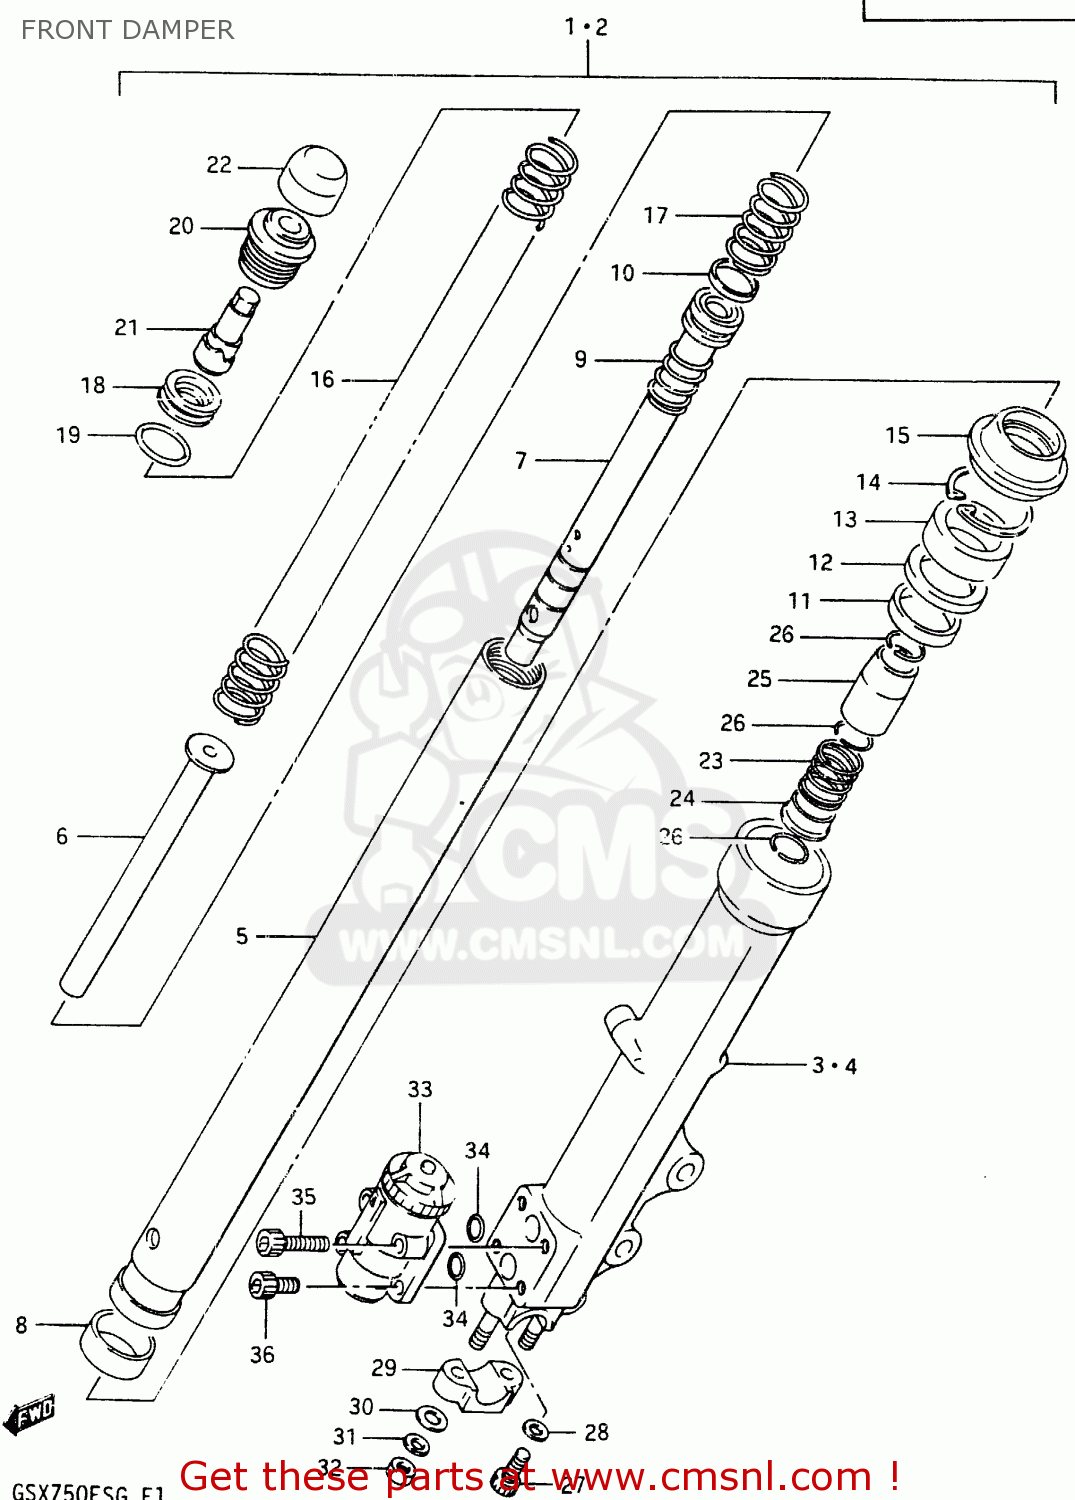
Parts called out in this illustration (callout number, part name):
1	DAMPER ASSY, RH
2	DAMPER ASSY, LH
3	TUBE, OUTER RH (BLACK)
4	TUBE, OUTER LH (BLACK)
5	TUBE, INNER
6	SEAT, INNER TUBE
7	CYLINDER
8	PISTON
9	SPRING REBOUND
10	RING,PISTON
11	BUSHING,GUIDE
12	SPACER,SEAL
13	OIL SEAL,FRONT FORK
14	CIRCLIP,INNTERNAL
15	SEAL,DUST
16	SPRING
17	SPRING, LOWER
18	SEAT,FRONT FORK SPRING
19	O RING
20	CAP,FORK INNER TUBE
21	ADJUSTER,SPRING
22	CAP
23	SPRING, VALVE
24	VALVE, OIL LOCK PIECE
25	PIECE, OIL LOCK
26	RING,STOPPER
27	BOLT(8X27)
28	GASKET (NAS)
29	HOLDER,AXLE
30	WASHER
31	WASHER,LOCK,8.
32	NUT
33	P.D.F ASSY
34	O RING,FR FORK
35	BOLT
36	BOLT
